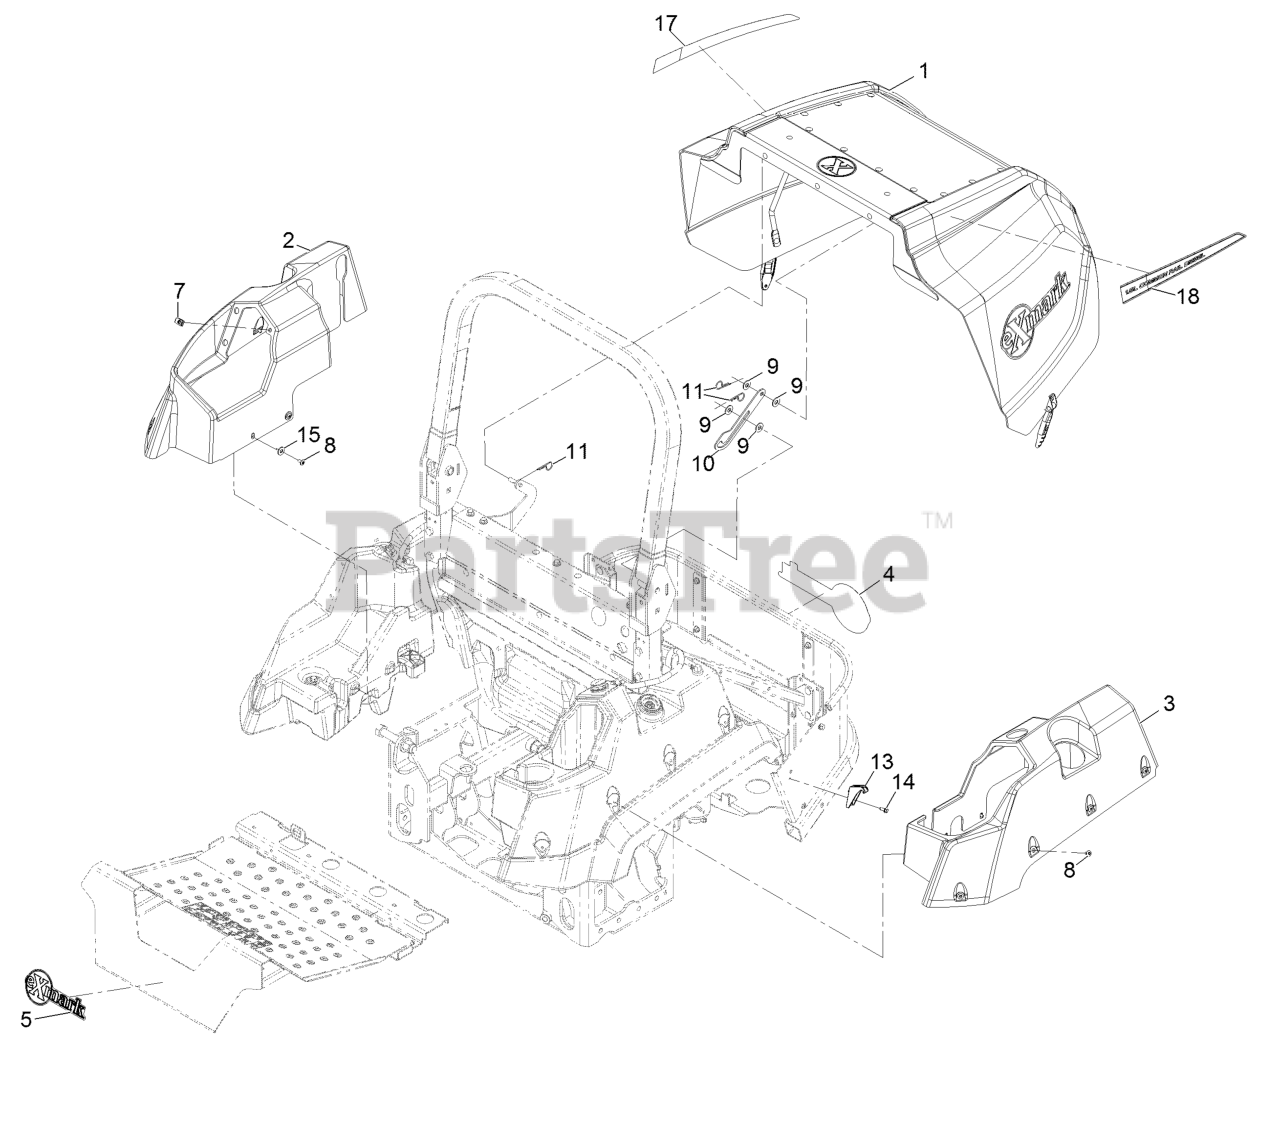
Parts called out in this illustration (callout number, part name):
1	Hood ASM
2	Cover-Tank, RH
3	Cover-Tank, LH
4	Decal-Exmark
5	Decal-Exmark
7	Nut-Retainer-Panel 1/4-20
8	Screw-Torx
9	Washer-3/8 Std
10	Prop-Hood
11	Pin-Cotter, Hair
13	Latch-Catch
14	Screw-HWH 1/4-20 X .62
17	Decal-Common Rail Diesel-RH
18	Decal-Common Rail Diesel-LH
